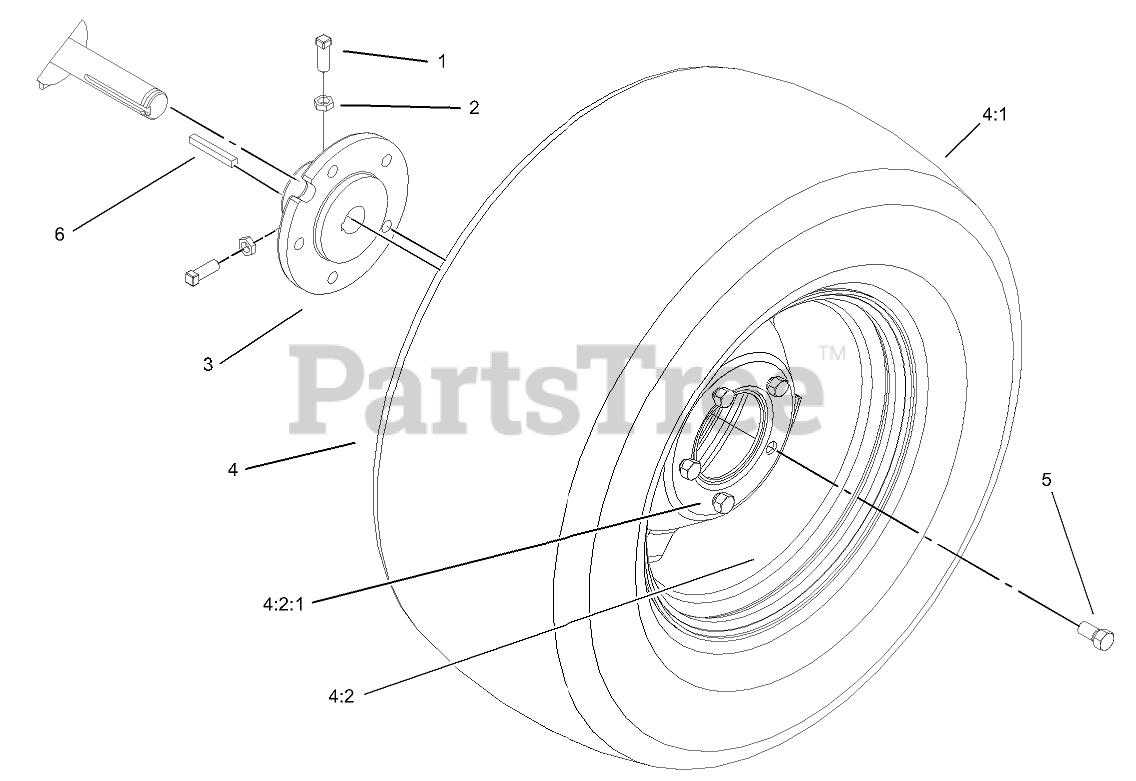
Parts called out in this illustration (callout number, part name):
1	SCREW-SET, SQH
2	NUT-JAM
3	HUB-WHEEL
4	REAR WHEEL & TIRE ASM
4:2	WHEEL
4:2:1	VALVE
5	BOLT-LUG
6	KEY-SQUARE
